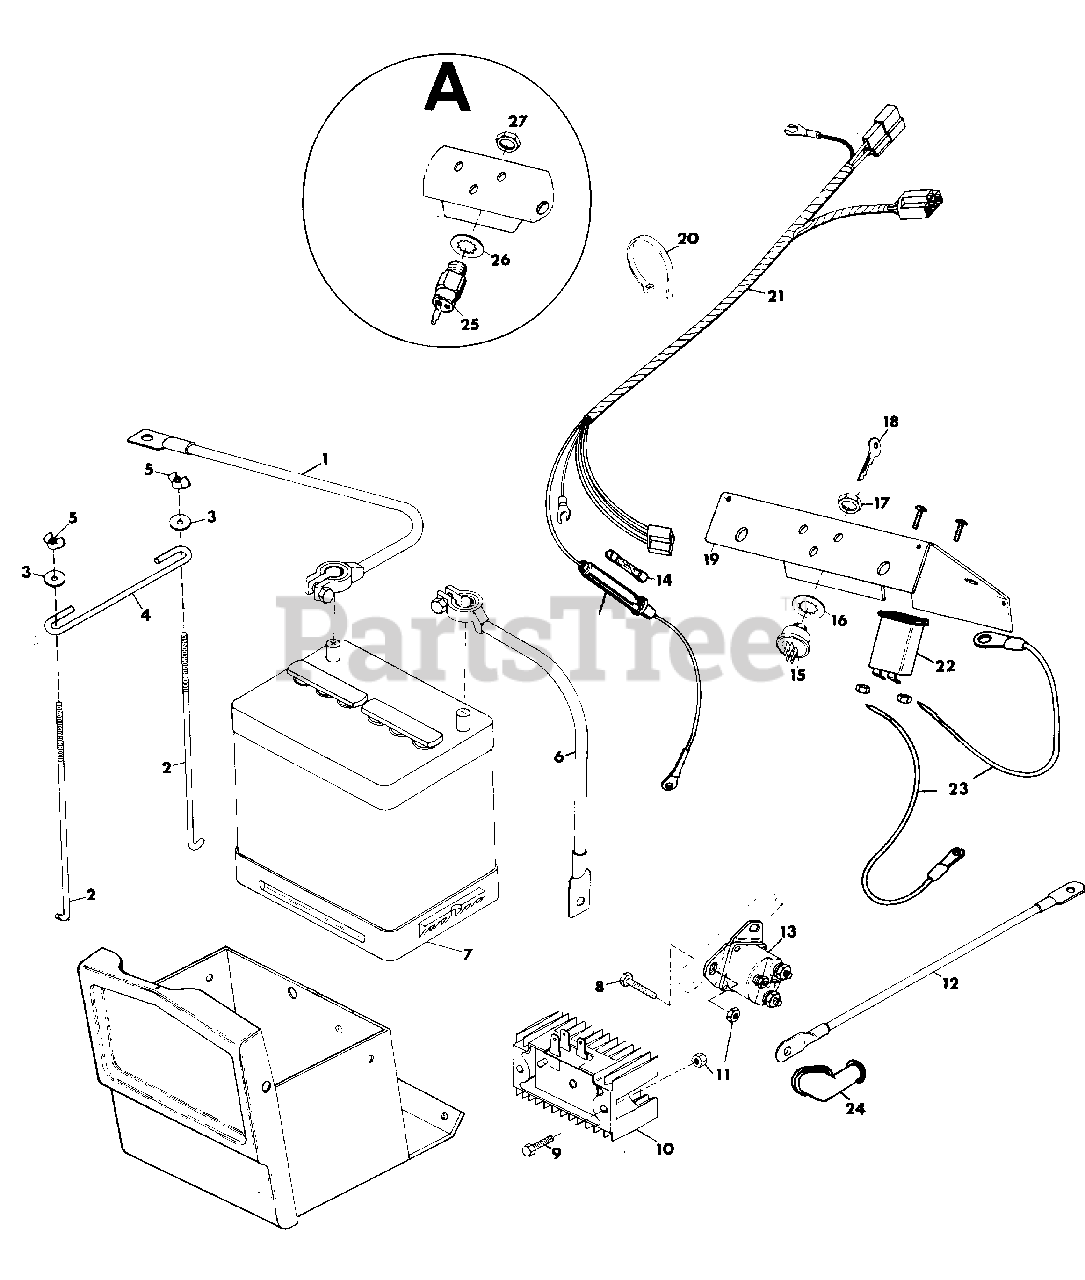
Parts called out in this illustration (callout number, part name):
1	CABLE, POSITIVE BATTERY
2	BOLT, HOLD-DOWN
3	WASHER, FLAT .313X.875X.065
4	HOLD-DOWN, BATTERY
5	NUT, WING 1/4-20
6	CABLE, NEGATIVE BATTERY
7	BATTERY, 12 VOLT MAINTENANCE-FREE
8	BOLT, HEX 1/4-20X1.75
9	BOLT, HEX 1/4-20X.75(MODEL 5665)
10	REGULATOR, RECTIFIER(MODEL 5665)
11	NUT, HEX 1/4-20(MODEL 5260)
11	NUT, HEX 1/4-20(MODEL 5665)
12	CABLE, MAGNETIC SWITCH TO STARTER
13	SWITCH, MAGNETIC
14	FUSE, 30 AMP ACC-30
15	SWITCH, IGNITION
16	WASHER, LOCK(MODEL 5260, 5665)
17	NUT, JAM 9/16-24(MODEL 5260, 5665)
18	KEY, IGNITION SWITCH
19	PANEL, INSTRUMENT(MODEL 5200, 5240, 5645)
19	PANEL, INSTRUMENT(MODEL 5260,5665)
19	PANEL, INSTRUMENT(MODEL 5665)
20	TIE, CABLE
21	HARNESS, WIRING 3 AMP(MODEL 5260,5665)
21	HARNESS, WIRING 15 AMP(MODEL 5665)
22	HOURMETER(MODEL 5665)
23	WIRE, INSTRUMENT PANEL(MODEL 5665)
24	BOOT, BATTERY CABLE(MODEL 5260, 5665)
25	SWITCH, IGNITION
26	WASHER, LOCK(MODEL 5200, 5240, 5645)
27	NUT, JAM 5/8-32(MODEL 5200, 5240, 5645)
